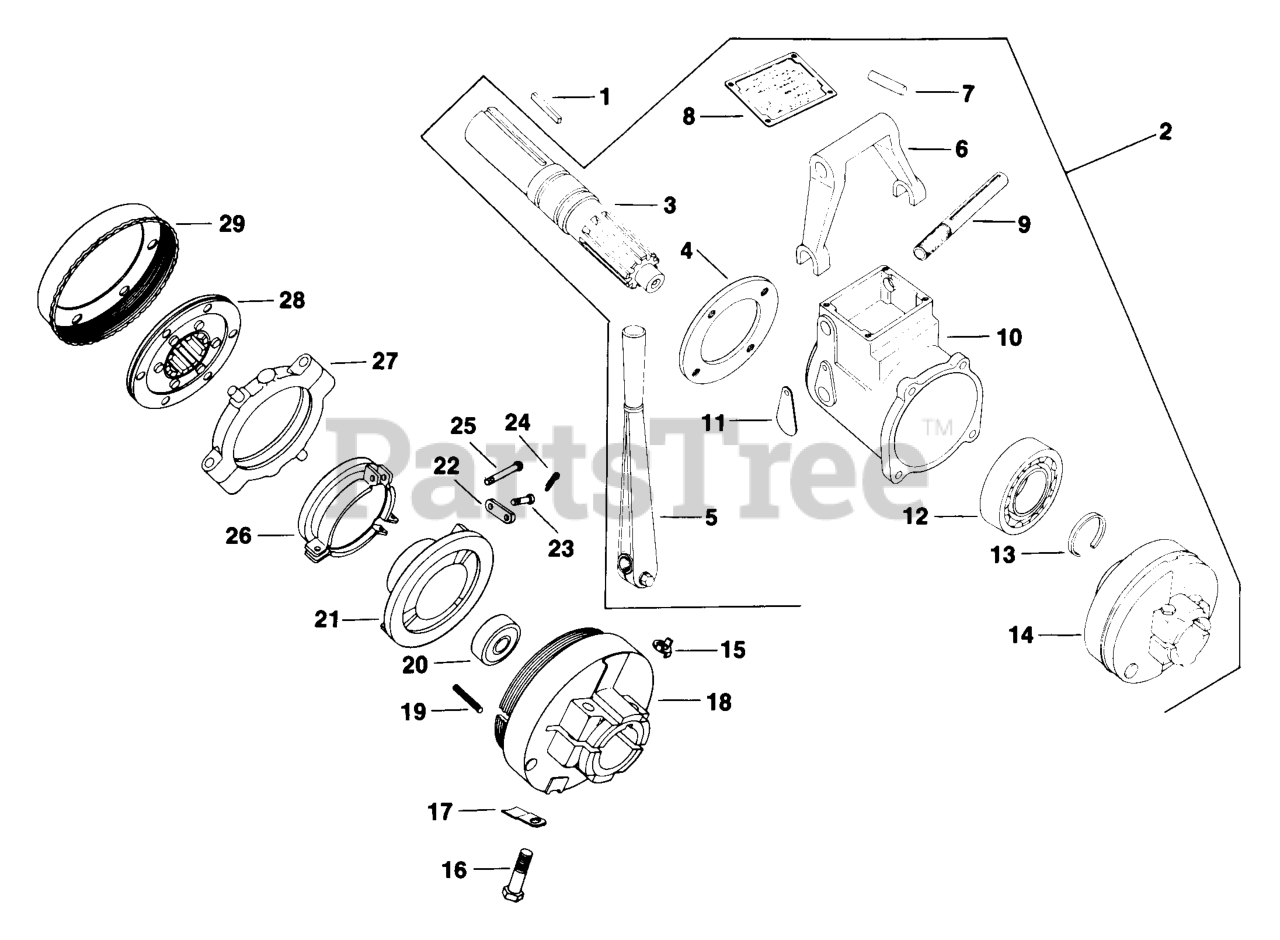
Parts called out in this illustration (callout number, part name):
2	CLUTCH - DISCONTINUED
3	SHAFT - DISCONTINUED
4	PLATE - DISCONTINUED
5	LEVER - DISCONTINUED
6	YOKE - USE 24 471 01
9	SHAFT - DISCONTINUED
12	BEARING - DISCONTINUED
13	BASE - DISCONTINUED
15	LOCK - DISCONTINUED
19	SPRING - DISCONTINUED
20	Bearing
21	PLATE - DISCONTINUED
22	BEARING - DISCONTINUED
26	PLATE - DISCONTINUED
27	BEARING - DISCONTINUED
28	SLEEVE - DISCONTINUED
